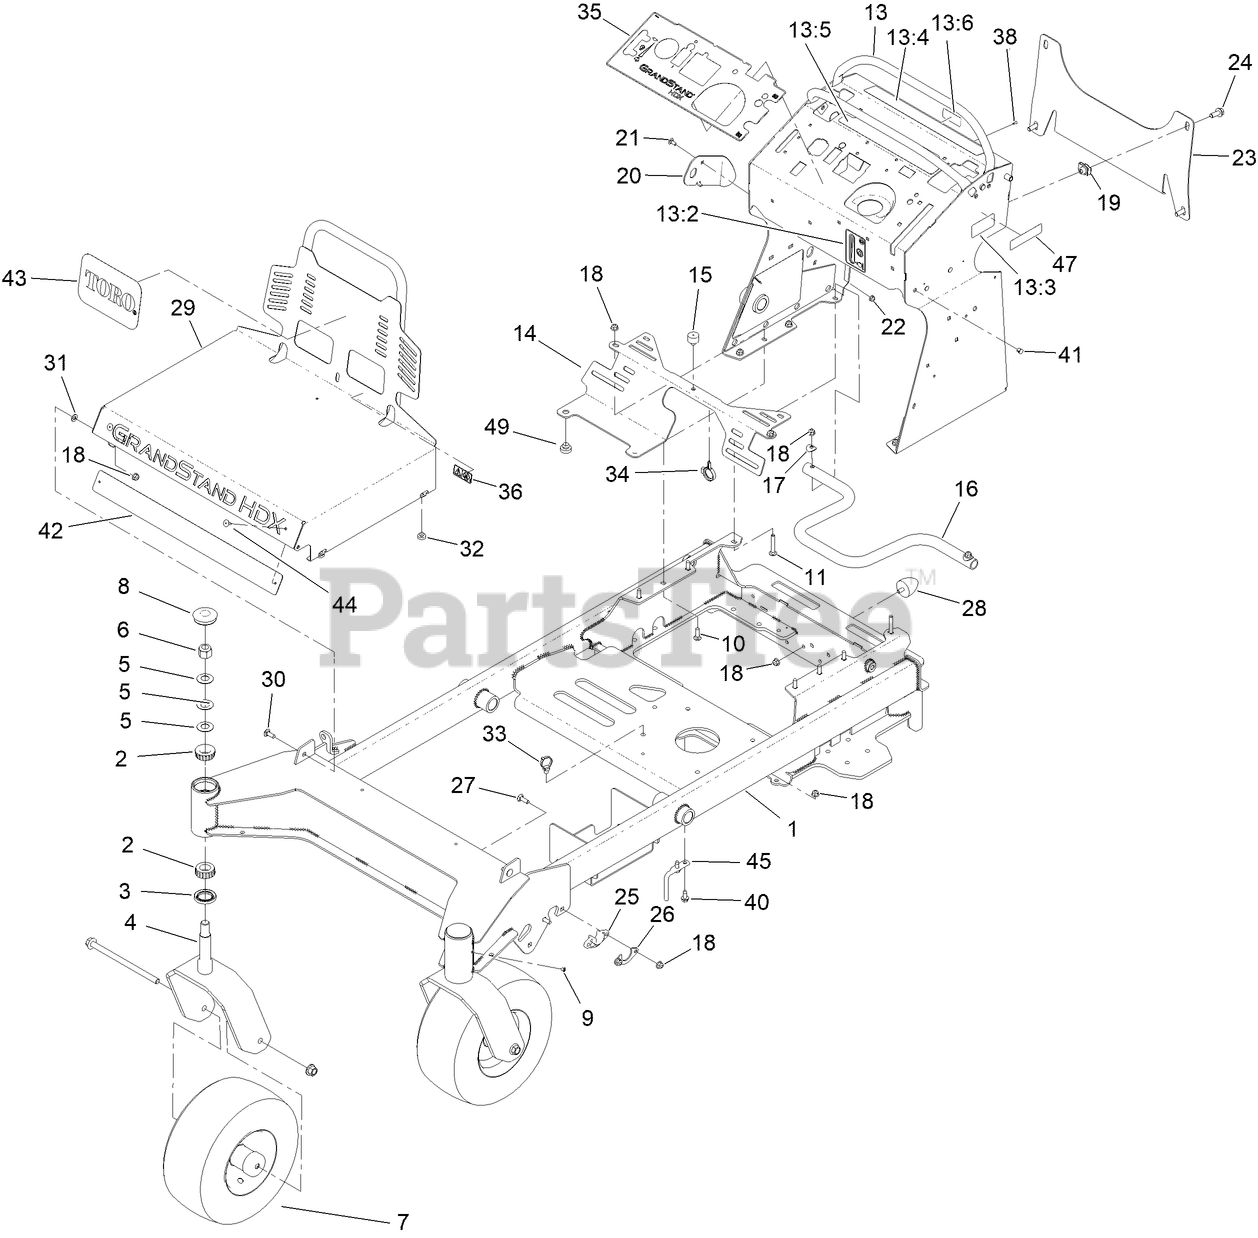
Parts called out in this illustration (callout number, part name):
1	FRAME-60 [RED]
2	BEARING-ROLLER, TAPERED
3	SEAL-GREASE
4	CASTER-FORK [RED]
5	WASHER-BELLVILLE
6	NUT-LOCK, NI
7	ASM-WHEEL BRGS AXLE 13X6.50-6
8	CAP,GREASE
10	BOLT-CARR
11	BOLT-CARR
13	TOWER DECAL ASM
13:2	DECAL-OIL LEVEL
13:3	DECAL-FILL, FUEL
13:4	DECAL-WARNING
13:5	DECAL-CONTROLS
13:6	DECAL - FUSE
14	SUPPORT, FUEL TANK
15	BUMPER-GROMMET
16	TUBE-FUEL TANK MOUNT
17	WASHER
18	NUT-HF, NI
19	NUT-TINNERMAN
20	PLATE-STRIKER
21	SCREW-CARR
22	NUT-HF
23	BRACKET-CROSS
24	SCREW-HHF
25	BEARING-FLANGE
26	GUSSET-LIFT, DECK
27	SCREW-CARR
28	BUMPER-RUBBER
29	ASM-ENGINE GUARD [SERVICE]
30	BOLT-CARR
31	SPACER-NYLON
32	BUMPER
33	CLIP-TIE
34	CLAMP-HOSE
35	DECAL-PANEL CONTROL, BRIGGS
36	DECAL-WARNING, NO RIDERS
38	RIVET-POP
40	SCREW-HWHTF
41	DOME PANEL PLUG
42	PLATE-BACKING
44	RIVET-POP
45	GUIDE-BELT
47	DECAL-SPARK ARRESTER
49	BUMPER-RUBBER
